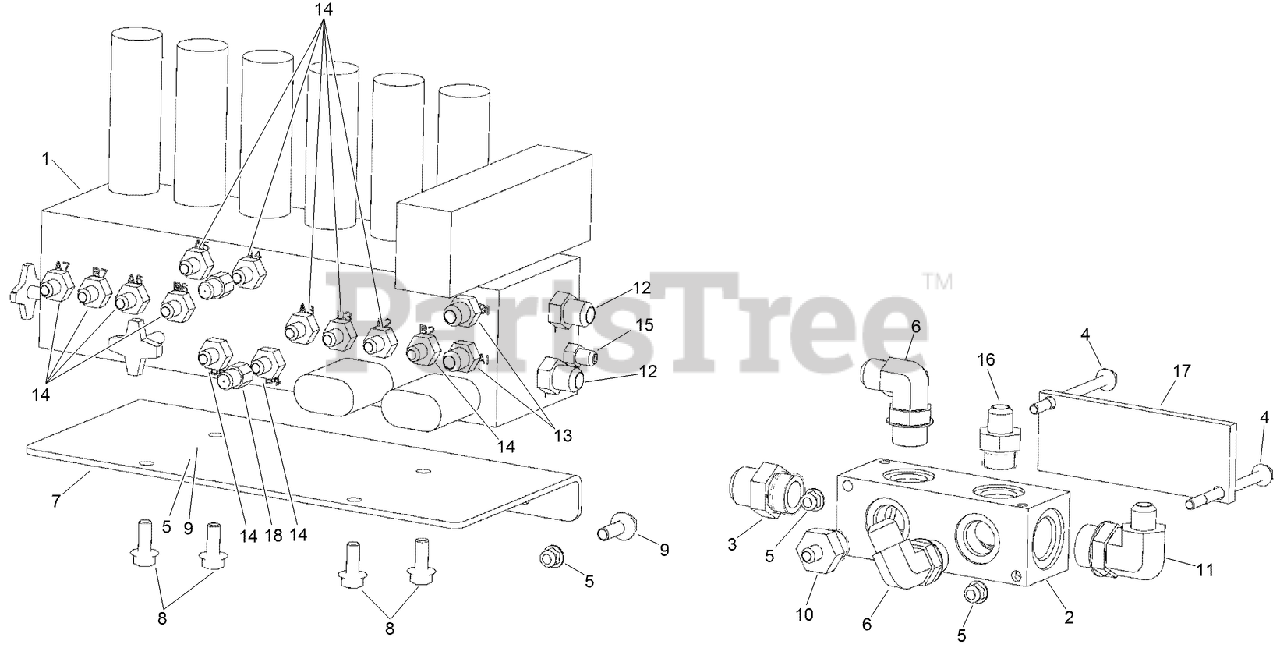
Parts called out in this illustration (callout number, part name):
1	MANIFOLD - Main HIC Valve
2	MANIFOLD ASM (HYD RETURN)
3	FITTING-STRAIGHT
4	SCREW, METRIC FLANGE w/BODY - M8 x 110
5	NUT-TORQUE, PREVAILING
6	ELBOW-90 Adj 37FL 3/4 Tube
7	PLATE - Filter Mount
8	SCREW-FLANGE
9	SCREW-HH
10	ADAPTER-STRAIGHT
11	ELBOW-90, ADJ
12	CONNECTOR-Str Thd 5/8, 37FL-ORB 5/8
13	CONNECTOR-Str Thd 1/2, 37FL-ORB 1/2
14	CONNECTOR
15	ADAPTER-STRAIGHT
16	FITTING-STRAIGHT
17	SPACER
18	ORIFICE - 0.047 Inline
